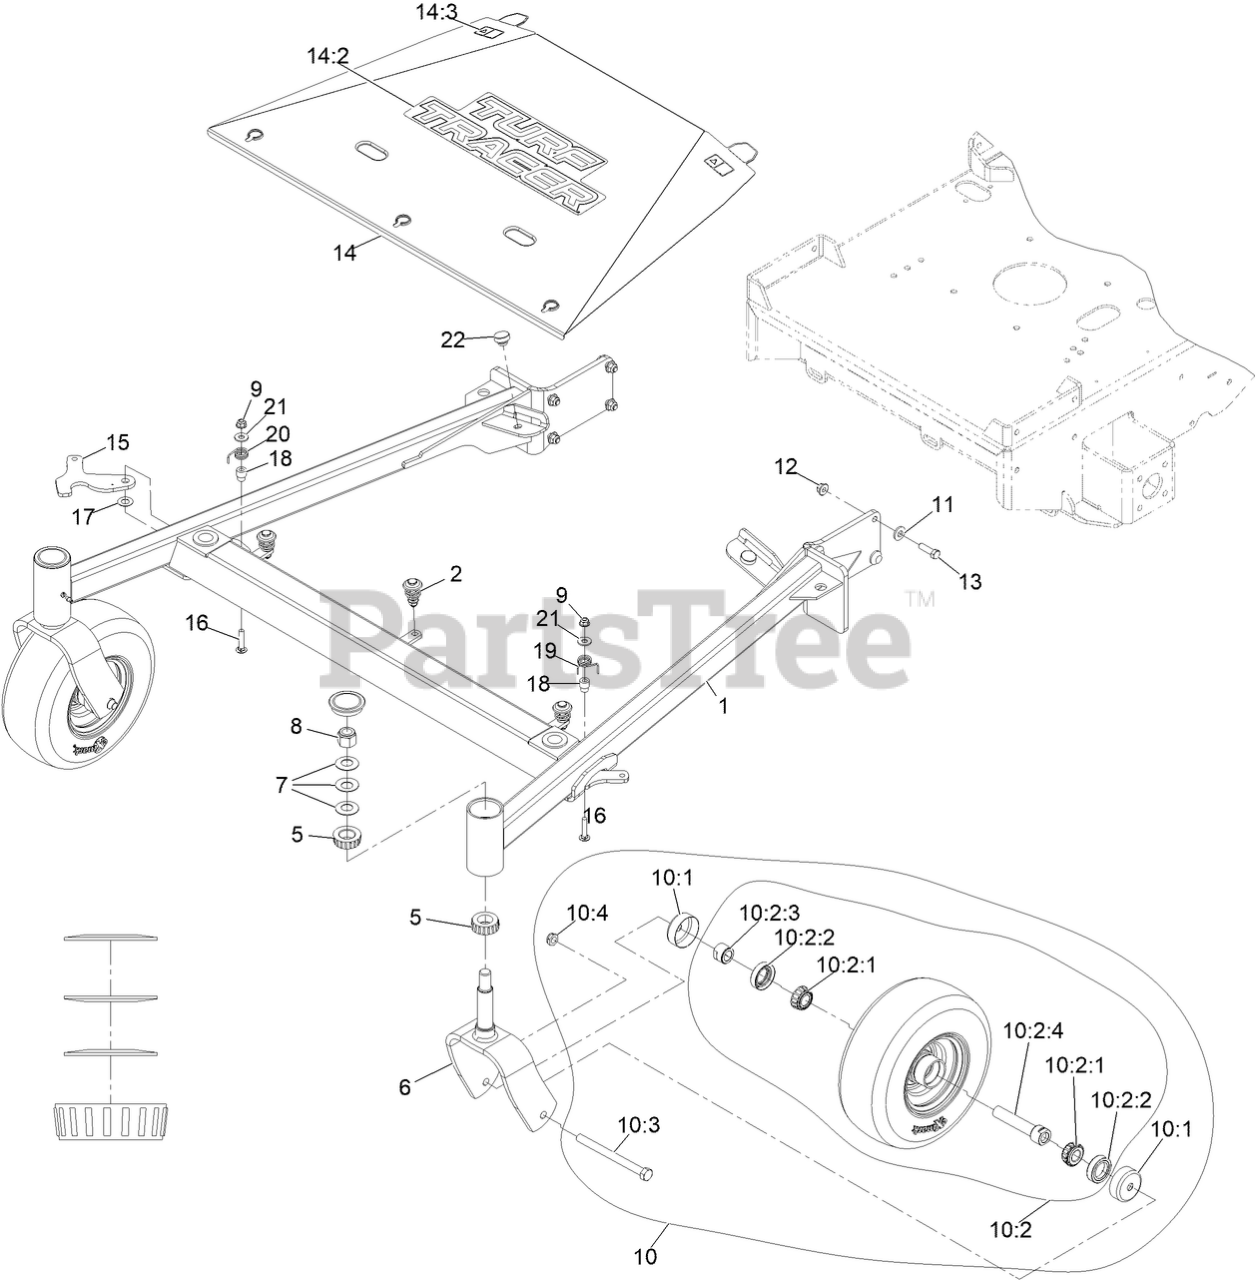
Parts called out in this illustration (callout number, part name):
1	ASM-60" Ttx Front Frame
2	HOOD RETAINER, TURF TRACER
5	Cone-Bearing Tapered Roller
6	WLD, CASTER FORK
7	WASHER-BELLVILLE
8	NUT-LOCK, NI
9	NUT-HF, NI
10	ASM,WHEEL&BEARINGS
10:1	GUARD-SEAL
10:2	Wheel And Bearing ASM
10:2:1	BEARING-CONE, TAPERED ROLLER
10:2:2	SEAL-CASTER
10:2:3	SPACER-NUT
10:2:4	CASTER AXLE ASM
10:3	SCREW-HH
10:4	NUT-HEX
11	WASHER-BELLEVILLE
12	NUT-HF, NI
13	SCREW-HH
14	ASM-60" Ttx Center Shield
14:2	DECAL-TURF TRACER
14:3	DECAL-WARNING
15	LATCH, DECK HEIGHT
16	BOLT-CARR
17	Washer-Plastic
18	COLLAR-BASKET
19	SPRING-TORSION, LH (YELLOW)
20	Spring-Torsion, RH
21	WASHER-FLAT
22	BUMPER-RUBBER
